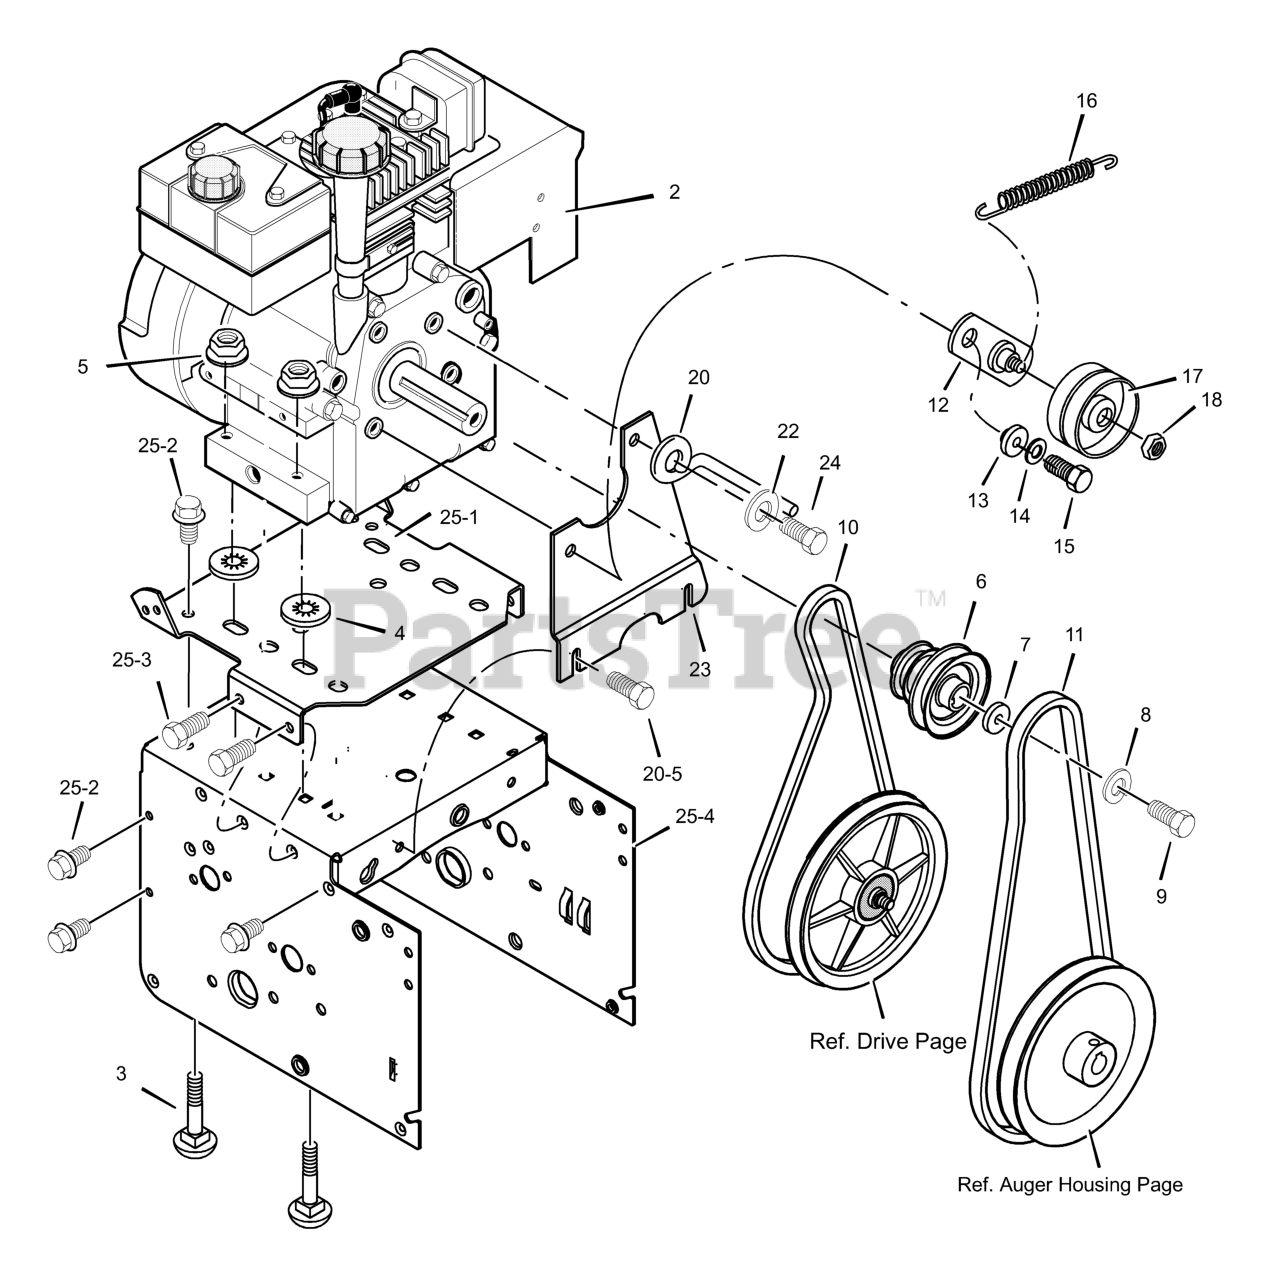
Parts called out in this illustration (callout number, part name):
2	ENGINE
3	BOLT, CARRIAGE 5/16-18
4	RETAINER, PUSH
5	NUT, HEX 5/16-18
6	PULLEY, ENGINE
7	WASHER
8	WASHER .38ID
9	SCREW, 3/8-24 x 1.00
10	BELT, DRIVE V 3L
11	BELT, AUGER V 4L
12	BRACKET ASSEMBLY, IDLER
13	BUSHING, IDLER BRACKET
14	WASHER, SPLIT
15	SCREW 5/16-24 X 1.00
16	SPRING, IDLER TRACTION DRIVE
17	PULLEY, IDLER
18	NUT, JAM 3/8-16
20	GUIDE, BELT
22	WASHER, SPTLK .31X.58X.08
23	PLATE, ANTI VIBRATION
24	SCREW, 5/16-24 x 1.00
25	FRAME ASSEMBLY
25-1	PLATE, ENGINE MOUNT
25-2	SCREW, TAP 1/4-20 X .63
25-3	SCREW, TAP 5/16-18 X .50
25-4	FRAME, MOTOR BOX
